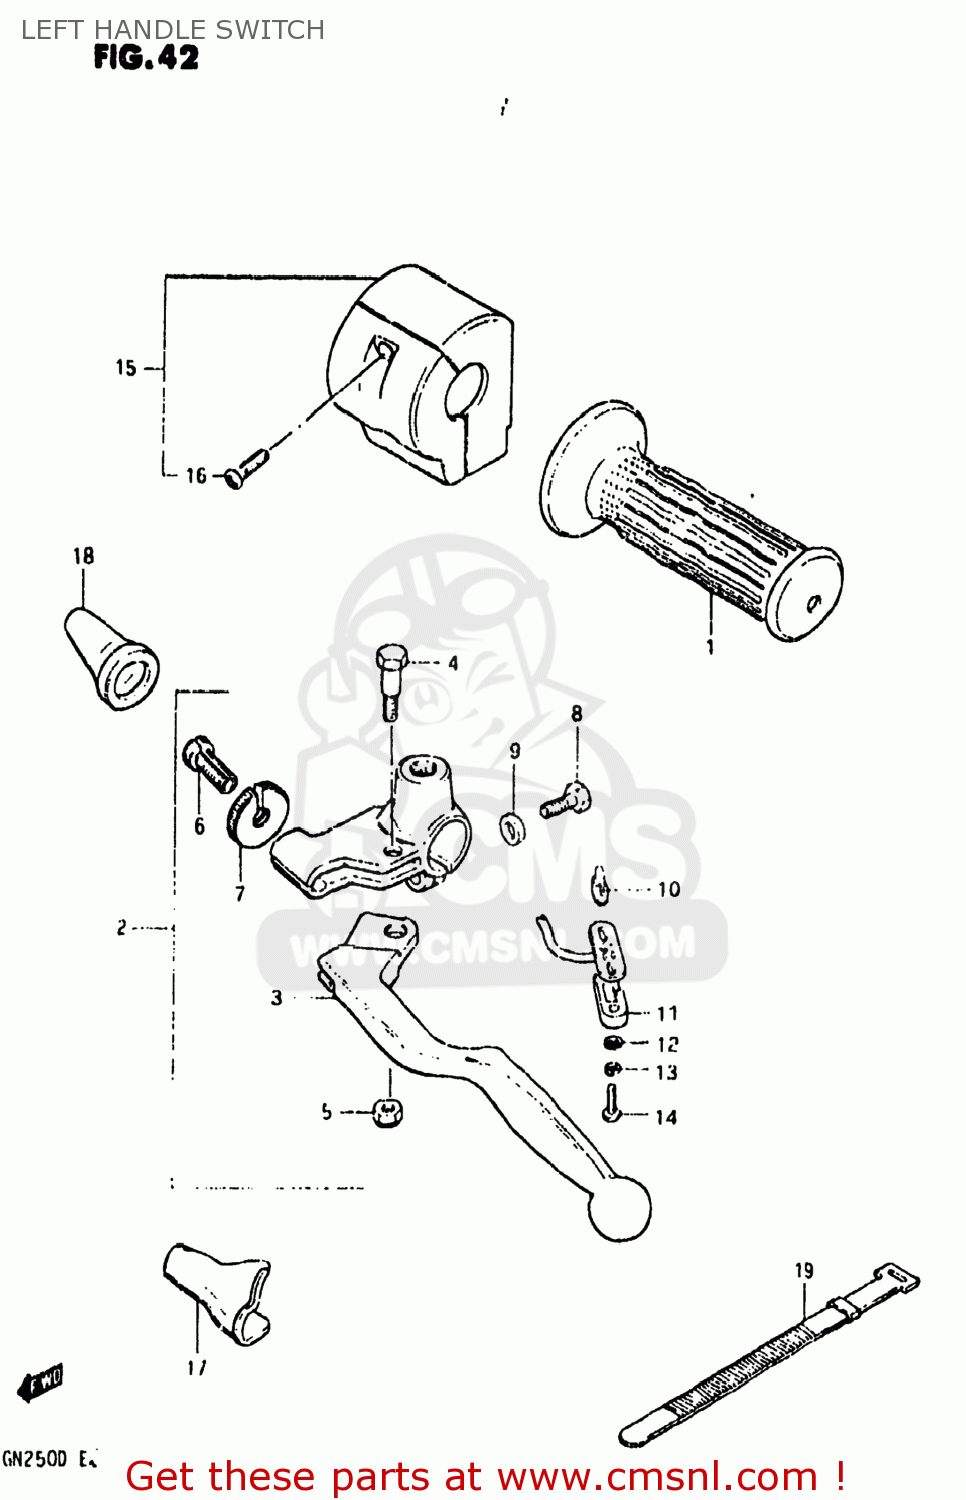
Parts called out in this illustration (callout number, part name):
1	GRIP,L
2	LEVER ASSEMBLY
3	LEVER,CLUTCH
4	BOLT,LEVER
5	NUT 6MM
6	ADJUSTER,CABLE
7	NUT,CABLE ADJUSTER
8	BOLT,CLUTCH LEVER HOLDER
9	SPACER
10	CONTACT,SWITCH
11	COVER,FR BK TERMINAL BASE
12	WASHER
13	LOCK WASHER
14	SCREW
15	SWITCH ASSEMBLY,HANDLE,LEFT
16	SCREW
17	COVER,CLUTCH LEVER
18	BOOT,CLUTCH CABLE
19	CLAMP(L:120)
